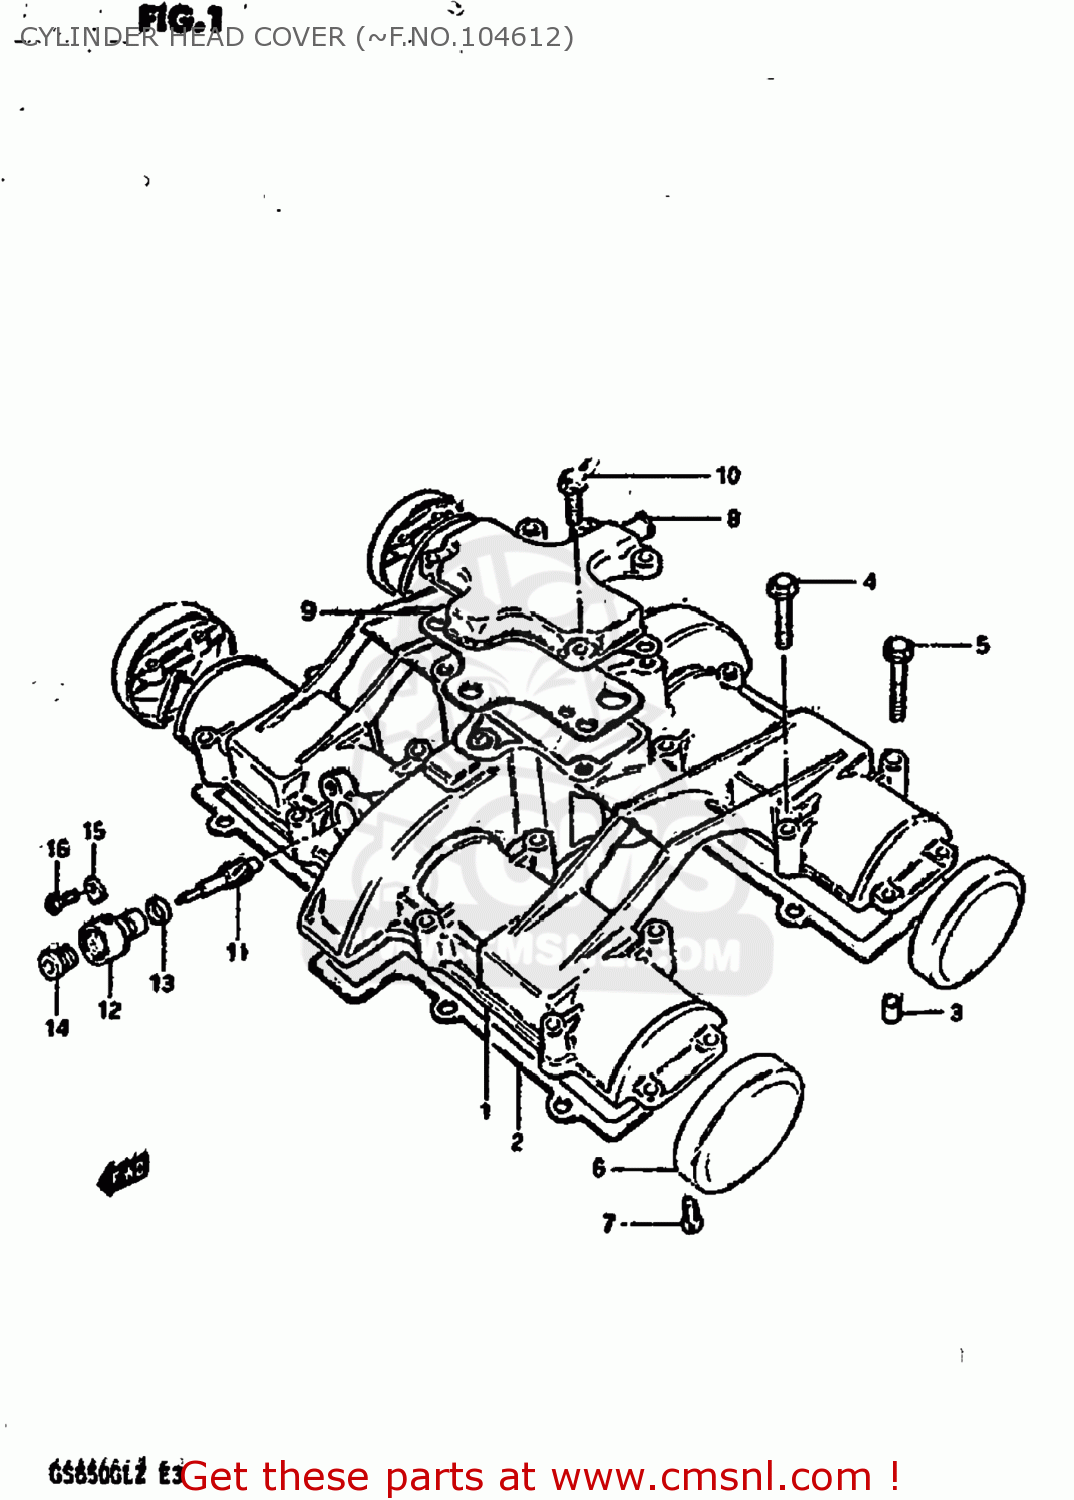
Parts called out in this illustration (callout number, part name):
1	COVER,CYLINDER HEAD
2	GASKET,CYLINDER HEAD COVER (MCA)
3	PIN(6.2X8X11)
4	BOLT
5	BOLT,UNDER
6	CAP,CYLINDER HEAD COVER
7	SCREW
8	COVER,BREATHER
9	GASKET (MCA)
10	BOLT,REAR
11	GEAR,TACHOMETER DRIVEN
12	SLEEVE,TACHOMETER DRIVE
13	SEAL,TACHOMETER DRIVEN
14	SEAL,OIL(5X12X8)
15	PLATE,TACH DRIVE GEAR SLEEVE
16	SCREW(5X12)
